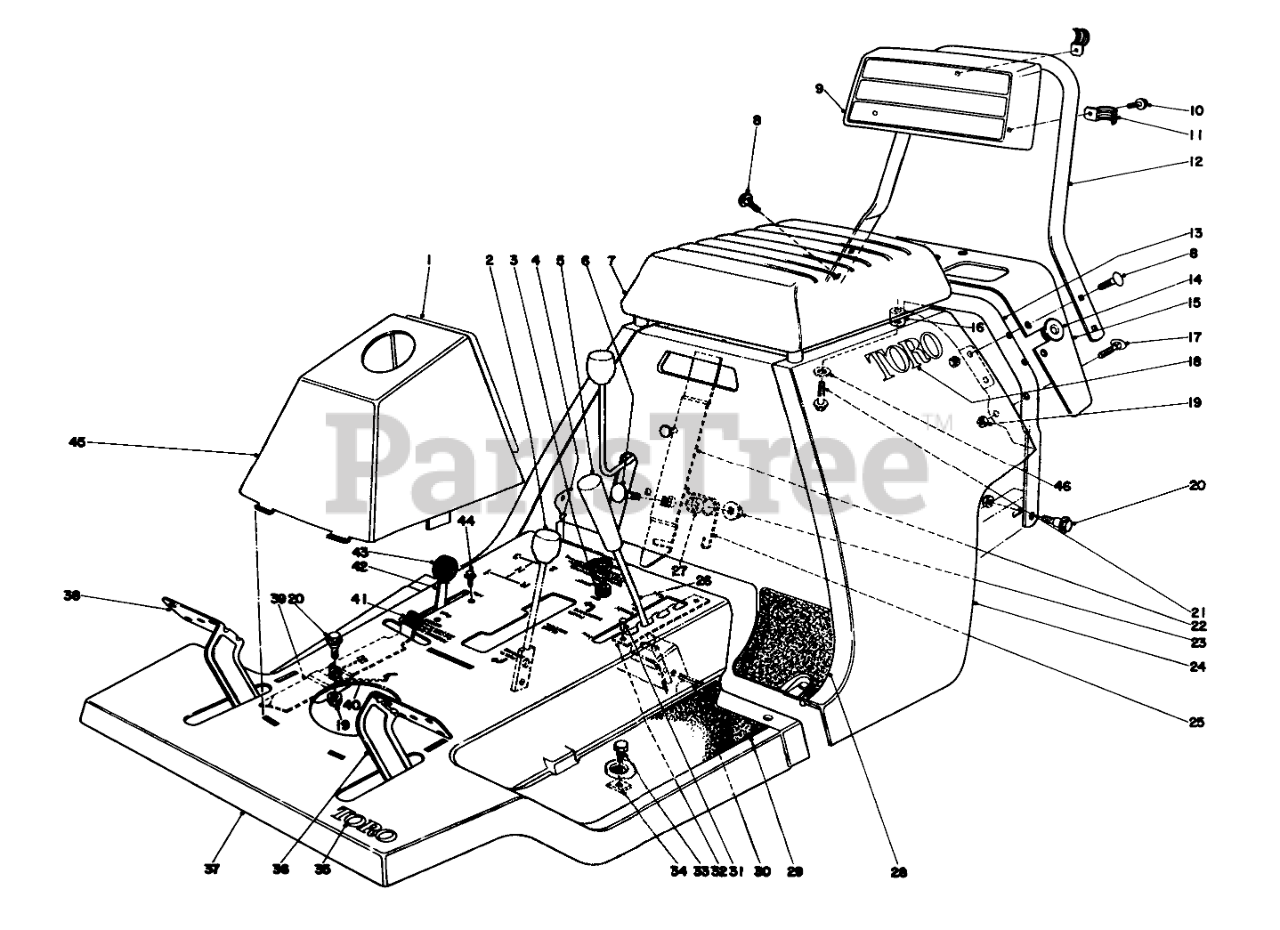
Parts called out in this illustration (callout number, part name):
1	Decal Tower
3	ON-OFF SWITCH 21-8-468
4	Key
5	KNOB-CONTROL
6	BOLT-CARR
8	SCREW-CARR
9	Backrest
10	SCREW-HHF
11	Clamp Conduit
12	Handle Upper
13	Handle Lower
14	Starting Ferrel
15	Extension Rear Body
16	Spacer
17	HANDLE SCREW
18	Decal
19	NUT-LOCK, CONE
20	SCREW-SHOULDER
21	HEX FLANGE SCREW
22	Handle Latch
23	NUT-HF
24	Rear Body
25	Latch Return Spring
26	Height of Cut Lever
27	Spacer
28	Heel Pad L.H.
29	Foot Tread L.H.
30	Pin-Roll
32	Height Adjustment Plate
33	Capscrew
34	NUT-TINNERMAN
35	DECAL
36	Clutch Pedal
37	Body Front (Incl. Ref. #31 & 32)
38	Brake Pedal
39	Parking Brake
40	SPRING-PARKING BRAKE
41	TIP-PARKING BRAKE
42	Throttle Control (Incl. Ref. #43)
44	8X1/2 SELF TAP SCREW
45	Tower
46	WASHER-FLAT
